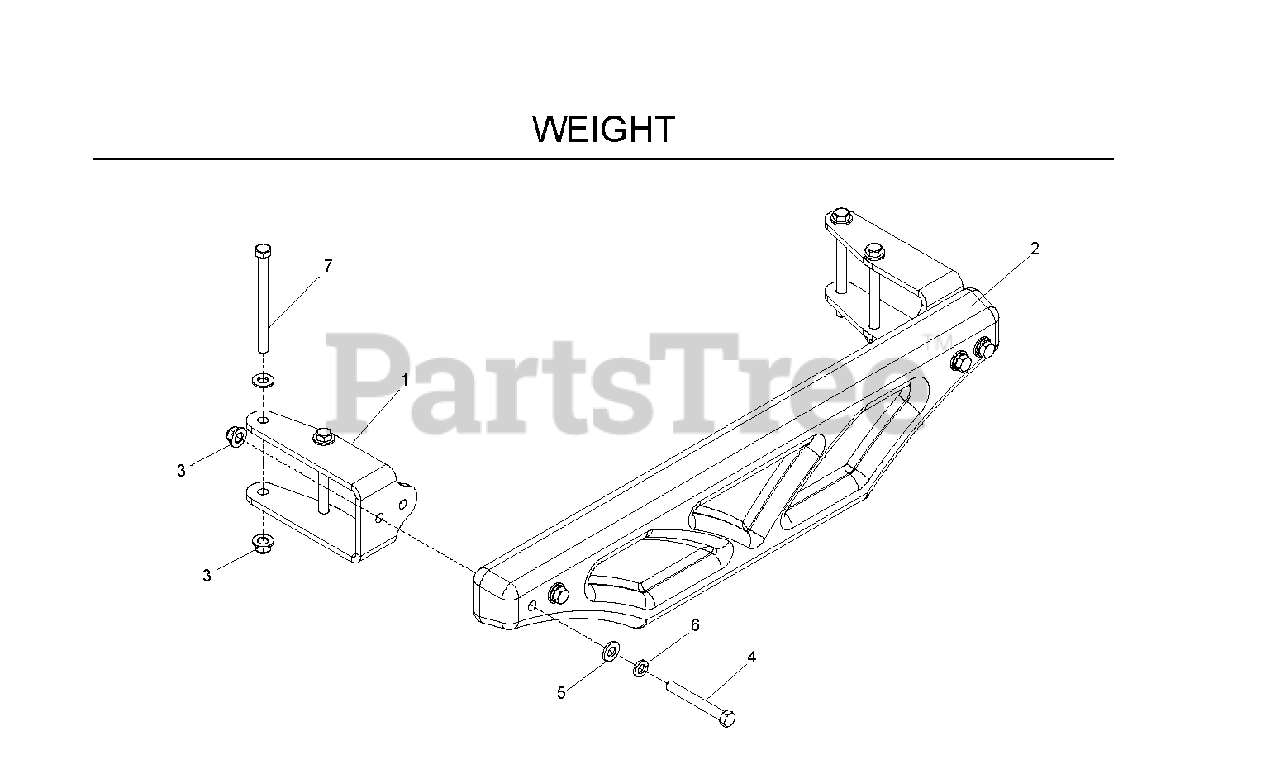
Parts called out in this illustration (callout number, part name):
1	BRACKET, WEIGHT, BLK
2	CAST WEIGHT
3	NUT 3/8-16 HEX FLG NYLOC ZD
4	HCS 3/8C X 3
5	WASHER 3/8 SAE FLAT
6	SLW 3/8 STD
7	TAPBOLT 3/8C X 4 1/2
